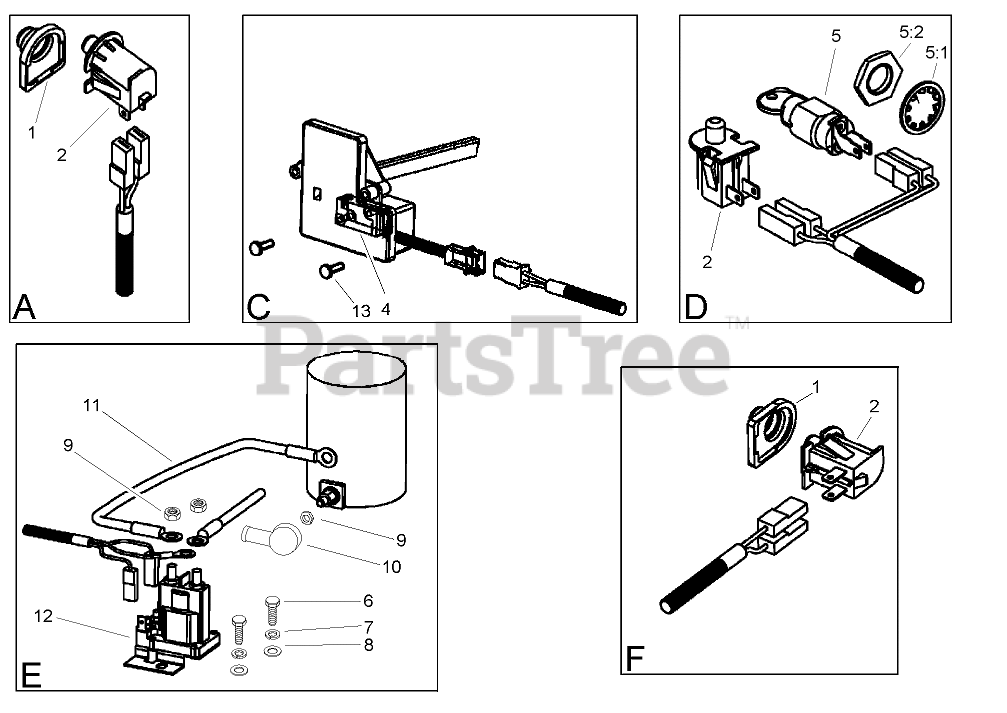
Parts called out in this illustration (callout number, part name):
1	COVER-PROTECTIVE
2	SWITCH-DELTA
4	SWITCH-OMRON
5	STARTER SWITCH ASM
5:1	WASHER-TOOTH, INTERNAL
5:2	NUT-HH
6	SCREW-HH
7	WASHER-SPRING
8	WASHER-FLAT
9	NUT-HHF
10	BOOT-RUBBER
11	LEAD-STARTER, ELECTRIC
12	SOLENOID
13	Screw
